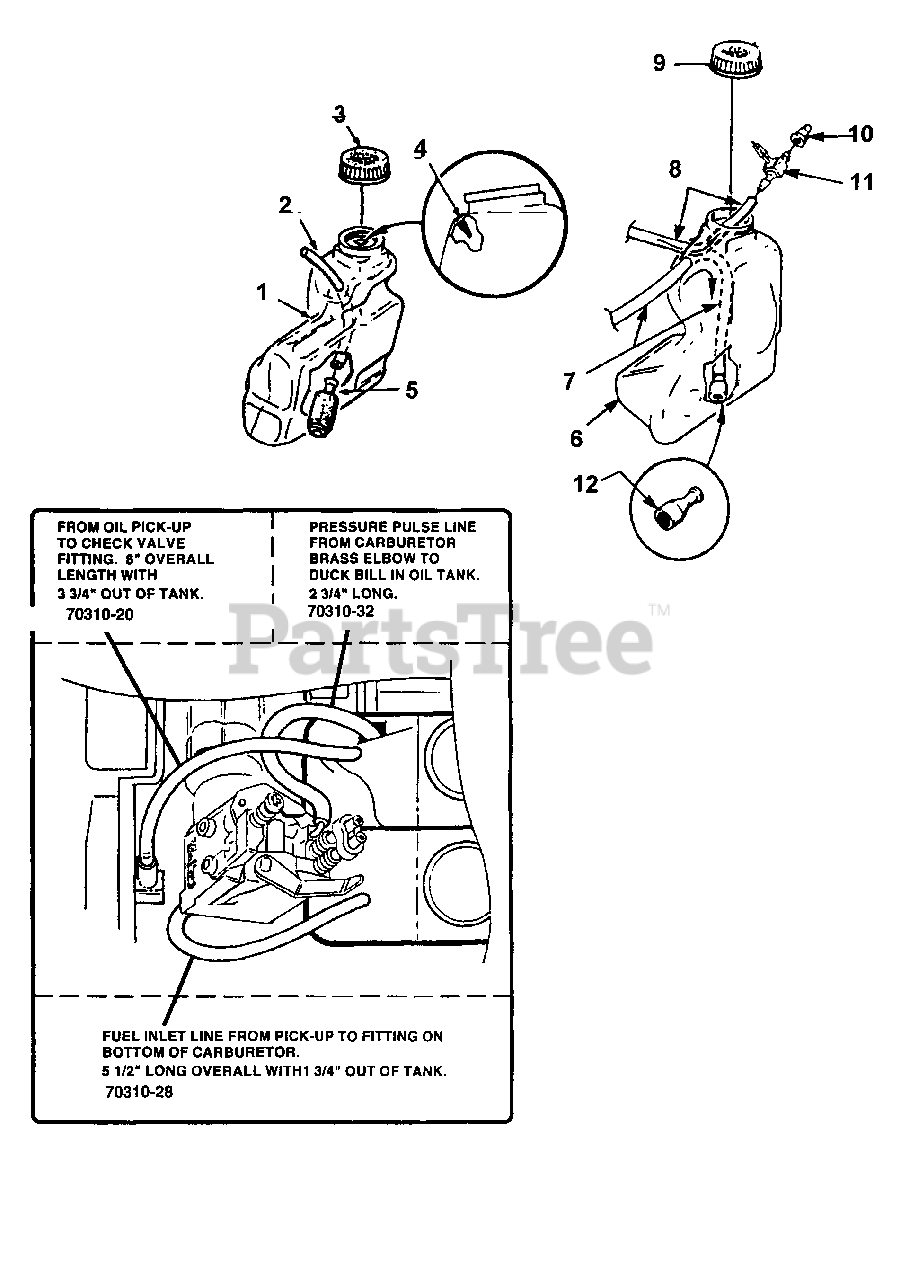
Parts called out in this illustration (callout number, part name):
1	FUEL TANK
2	TUBING, RUBBER (7")
3	CAP, FUEL
4	VALVE, DUCK BILL
5	FILTER, FUEL
6	OIL TANK
7	TUBING, RUBBER (8")
8	TUBING, RUBBER (2 1/2")
9	CAP, OIL
10	VALVE, DUCK BILL
11	FITTING, VENT
12	FILTER, OIL
7031020	TUBING 3-3/4"
7031028	TUBING 5-1/2"
7031032	TUBING 2-3/4"
